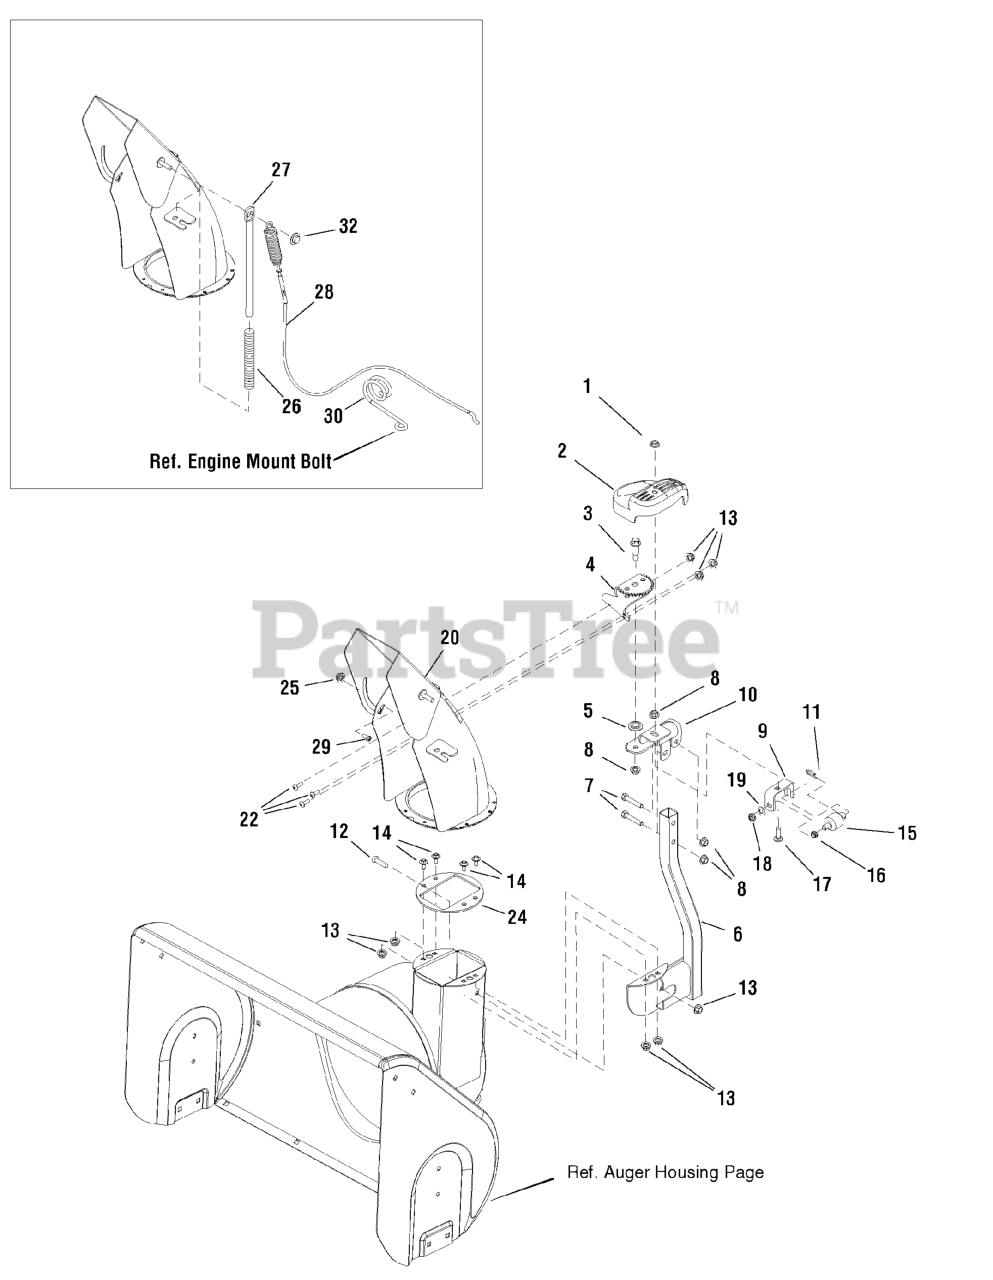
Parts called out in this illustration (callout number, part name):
1	NUT, Hex Flange 5/16-18 Two Way Lock
2	COVER, Gears
3	BOLT, Shoulder 5/16-18 G5
4	GEAR & SUPPORT ASSEMBLY, Chute
5	WASHER, Powdered Metal
6	CHUTE SUPPORT ASSEMBLY
7	SCREW, Hex Head Cap, 5/16-18 x 1 3/4
8	NUT, Hex KEPS 5/16-18 Conical Washer
9	SUPPORT, Worm "U" 10GA
10	SUPPORT, Gear & Chute 10GA
11	PIN, Hair Chute Gear
12	BOLT, CARRIAGE 0.25-20 x 0.75
13	NUT, Nylock Flanged, 1/4-20
14	SCREW, HEX WASHER
15	WORM, Chute L.H.
17	BOLT, 5/16-18 X 1.00
18	NUT, Hex Lock Jam ESNA Lite 3/8-24
19	WASHER, Cup
20	DISCHARGE CHUTE ASSEMBLY
22	SCREW, Truss Head, 1/4-20 x 3/4
24	GUIDE, CHUTE RING
25	NUT-HEX FLANGE.312-18 ESNA
26	SPRING, Compression
27	ROD, Spring
28	CABLE & SPRING ASSEMBLY
29	BOLT, CARRIAGE 5/16-18X.75
30	WIRE FORM, REMOTE CHUTE CABLE
32	NUT, Push for .312 DIA Stud Capped .625OD
